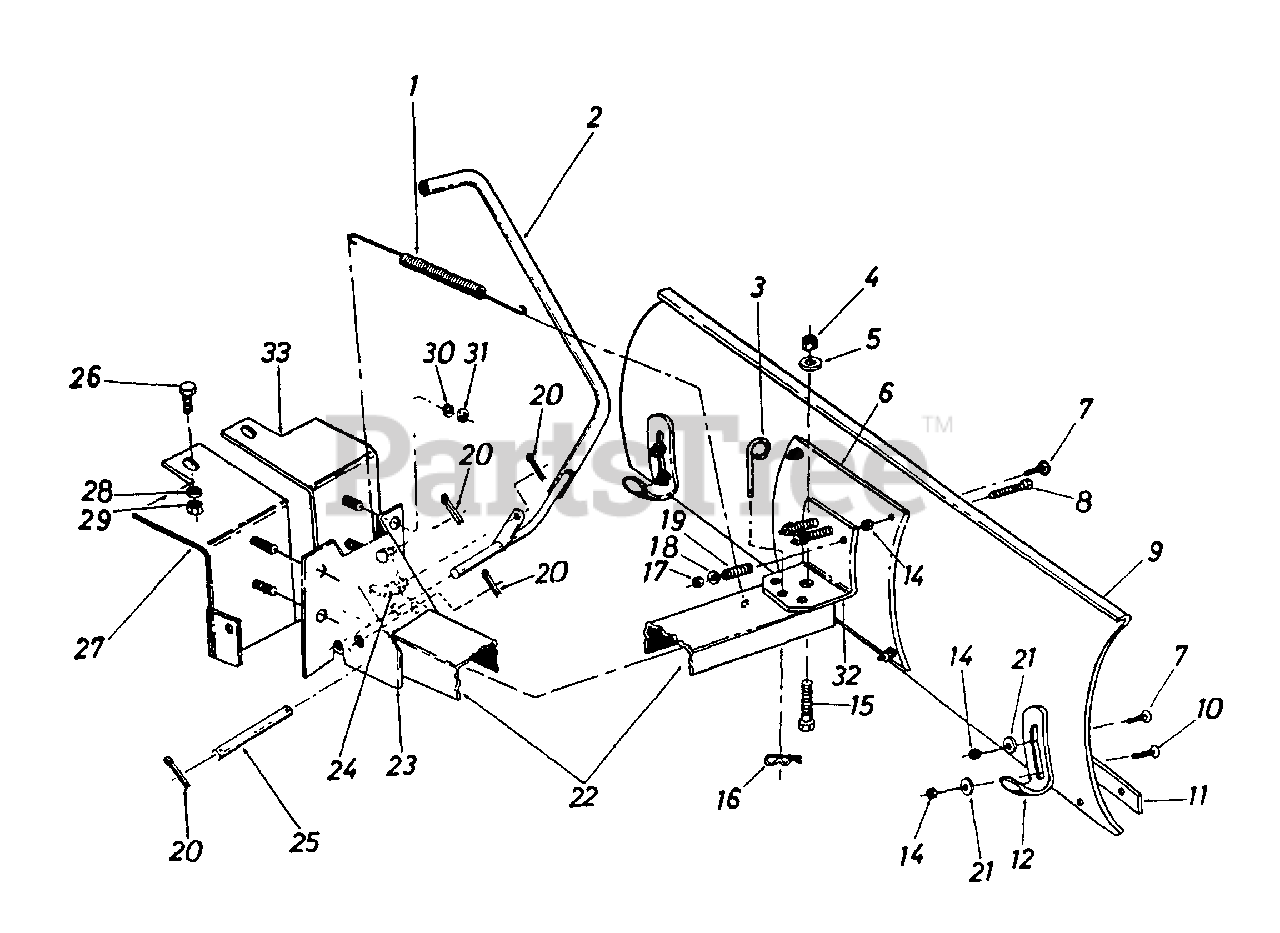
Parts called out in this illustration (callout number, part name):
1	Extension Spring
2	Lift Handle Ass'y.
3	Pivot Lock Pin
4	Hex Cent. L-Nut 1/2-13 Thd.
5	Fl-Wash. 17/32" I.D. x 1.25" Lg.
6	Reinforcement Plate
7	Carriage Bolt 5/16-18 x .75" Lg.
8	Hex Bolt 3/8-16 x 3.75" Lg. Grade 5
9	42" Blade
10	Carriage Bolt 5/16-18 x 1" Lg.
11	42" Wear Plate
12	Shoe Skid
14	Hex Cent. L-Nut 5/16-18 Thd.
15	Hex Bolt 1/2-13 x 1.25" Lg.
16	Int. Cotter Pin
17	Hex Cent. L-Nut 3/8-16 Thd.
18	Fl-Wash. 3/8" I.D.
19	Compression Spring
20	Cotter Pin 1/8" Dia. x 1" Lg.
21	Fl-Wash. 5/16" I.D.
22	Push Bar Channel
23	Pivot Support Bracket
24	Lift Link
25	Channel Pivot Shaft
26	Hex Bolt 3/8-16 x 1" Lg. Grade 5
27	Support Bracket - R.H.
28	L-Wash. 3/8" I.D.
29	Hex Nut 3/8-16 Thd.
30	L-Wash. 3/8" I.D.
31	Hex Jam Nut 3/8-16 Thd.
32	Support Bracket
33	Support Bracket - L.H.
